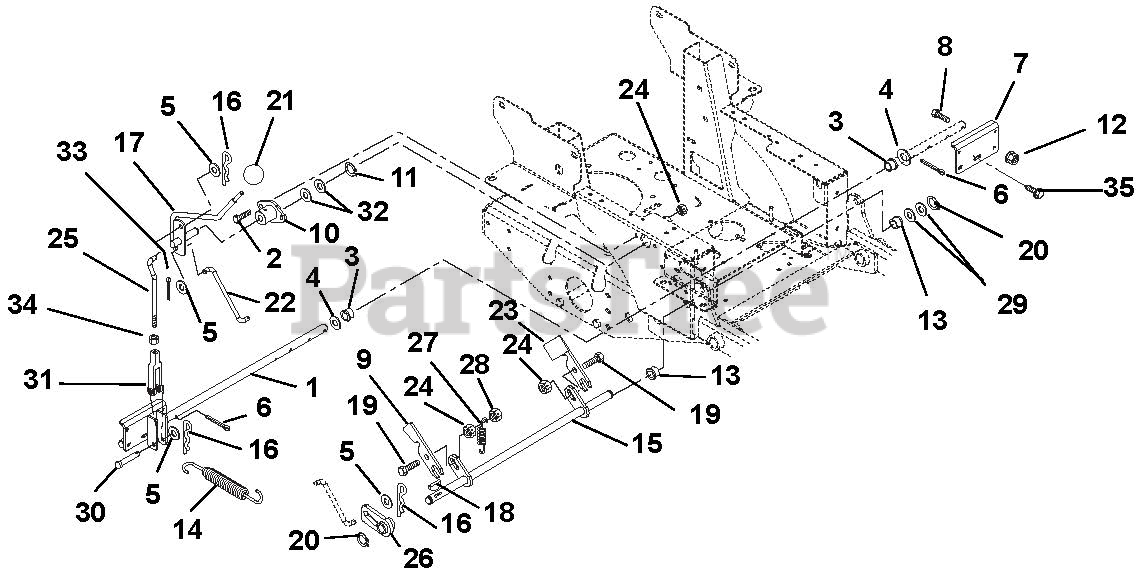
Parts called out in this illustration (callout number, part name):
1	Weldment, Brake Shaft
2	Bolt, Hex .31-18 x 1.00 Grade 5
3	Bushing, Flange .762 x 1.00 x .58 x 1.48 Nylon
4	Washer, Flat Steel .755 x 1.375 x .062
5	Washer, Flat Steel .406 x .812 x .065
6	Pin, Cotter .12 x 1.00 Extended Prong Square Cut
7	Paddle, Brake
8	Bolt, Hex .25-20 x 1.5 Grade 5
9	Slide, Interlocking Brake
10	Bushing, Flange
11	Ring, Retaining External .625 x .05
12	Nut, Nyloc Flange .25-20
13	Bushing, Flange .515 x .75 x .745 x 1.00
14	Spring, Engine Transmission
15	Weldment, Mechanical Brake
16	Pin, Hair
17	Weldment, Brake Actuating
18	Key, Woodruff .13 x .63
19	Bolt, Round Head Square Neck .31-18 x 1.25 Grade 5
20	Ring, Retaining External .50 x .05
21	Knob, Steering Lock
22	Linkage, Brake Actuating
23	Interlock, Safety Switch
24	Nut, Nyloc Flange 5/16-18
25	Linkage, Brake Compact-Z
26	Weldment, Parking Brake Hub
27	Spring, Tension .061 x .50 x 3.0
28	Nut, Locking Center .31-18
29	Washer, Flat Steel .505 x 1.00 x .062
30	Pin, Clevis .37 x 1.75
31	Clevis, .38-24 Adjustable Swivel
32	Washer, Flat Steel .630 x 1.250 x .062
33	Pin, Cotter .09 x .75 Extended Prong Square Cut
34	Nut, Jam .375-24
35	Screw, Tapping .31-18 x .75 Hex Washer Head Thread Rolling
